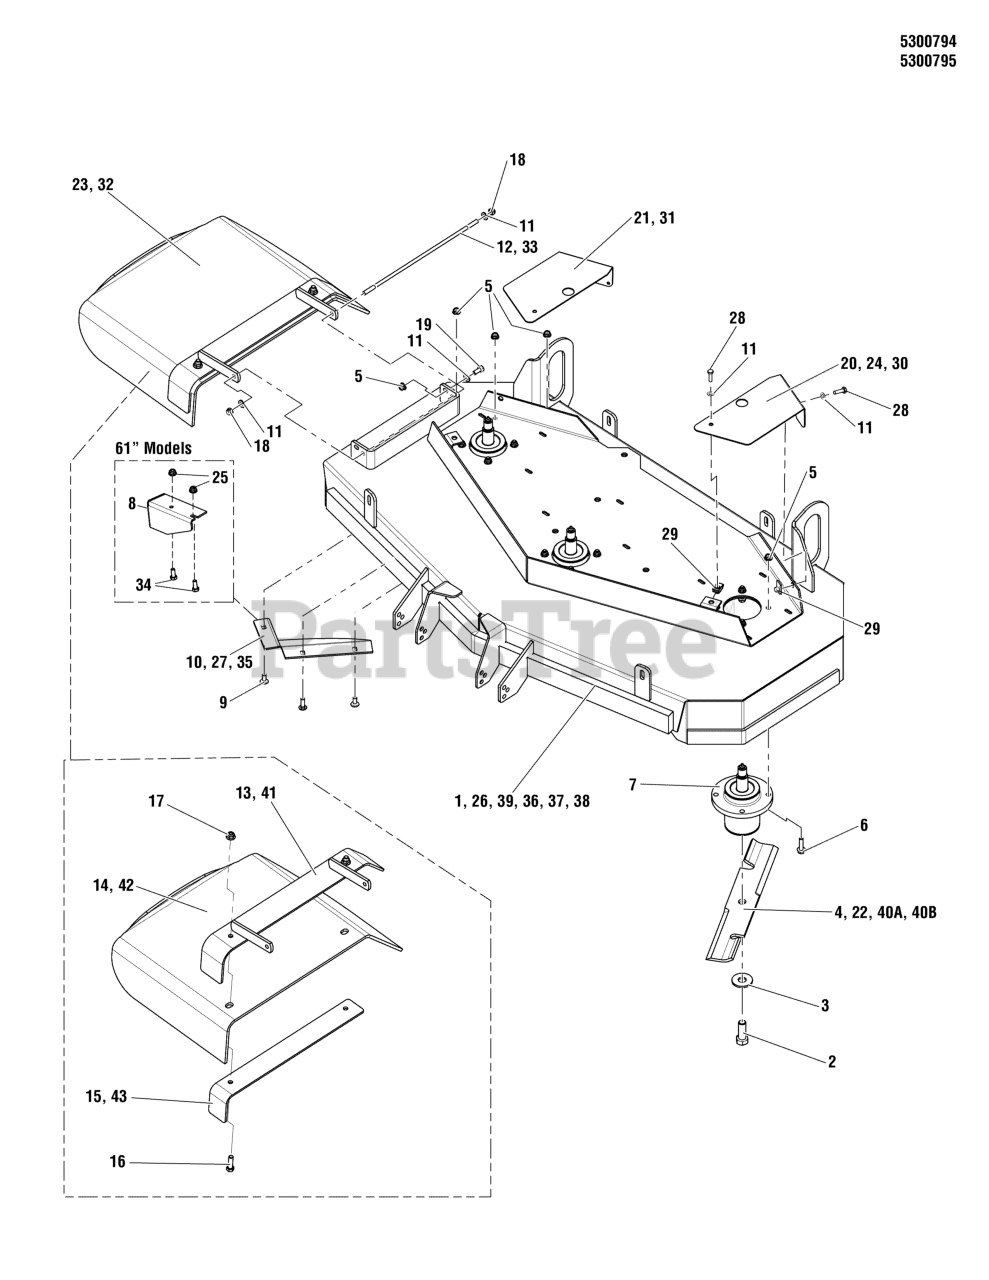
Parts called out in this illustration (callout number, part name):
1	DECK SHELL W/DECALS, 48, CCW
2	BOLT, 5/8-11 X 1-3/4 GR8
3	WASHER, 5/8" GRADE 8
4	BLADES, SET OF THREE (3); 16.25 X.25 X 2.5, 1 X 3.5
5	NUT, 5/16-18 HEX NYLOCK FLANGE
6	BOLT, 5/16-18 X 1-1/4" FLANGE
7	ASSM, SPINDLE, LOW PROFILE
8	PLATE, DEFLECTOR - BLK
9	CARRIAGE BOLT, 5/16-18 X 3/4
10	WELD, DISCHARGE BAFFLE, 48" - BLK
11	WASHER, 5/16" SAE
12	ROD, BRAKE LINKAGE
13	WELD, MOUNT, DISCHARGE CHUTE - BLK
14	CHUTE, DISCHARGE, BEND RUBBER, 44/48/52
15	SUPPORT, DISCHARGE CHUTE, 44/48/52 - BLK
16	BOLT, 3/8-16 X 1-1/2" GD5 CZ
17	NUT, 3/8-16 HEX NYLOCK FLANGE
18	NUT, 5/16-24 HEX NYLON LOCK
19	BOLT, 5/16-18 X 3/4 GD5
20	GUARD, DECK, 48" DDS - LH - RED
21	GUARD, DECK, 48" / 52" DDS - RH - RED
22	BLADE, 18" (SET OF THREE)(SV)
23	KIT, DISCHARGE CHUTE, 44/48/52
24	GUARD, DECK, 52" DDS - LH - RED
25	NUT, 5/16-18 HEX NYLOCK FLANGE
26	DECK SHELL W/DECALS, 52, CCW
27	WELD, DISCHARGE BAFFLE
28	BOLT, 5/16-18 X 1" GRD5
29	BODY CLIP, 5/16-18-7GA MATERIAL
30	GUARD, DECK 61" CCW - LH - RED
31	GUARD, DECK 61" CCW - RH - RED
32	PURCHASE INDIVIDUAL REPLACEMENT PARTS
33	ROD MOUNT, CHUTE, 61"
34	BOLT, 5/16-18 X 3/4, CARRIAGE
35	PLATE, DEFLECTOR, 52 - BLK
36	DECK SHELL W/DECALS, 52, CCW
37	DECK SHELL W/ DECALS
38	DECK SHELL W/ DECALS
39	DECK SHELL W/DECALS, 61, CCW
41	WELD, FRAME, CHUTE, 61" - RED
42	CHUTE, DISCHARGE, RUBBER, 61/72, BENT
